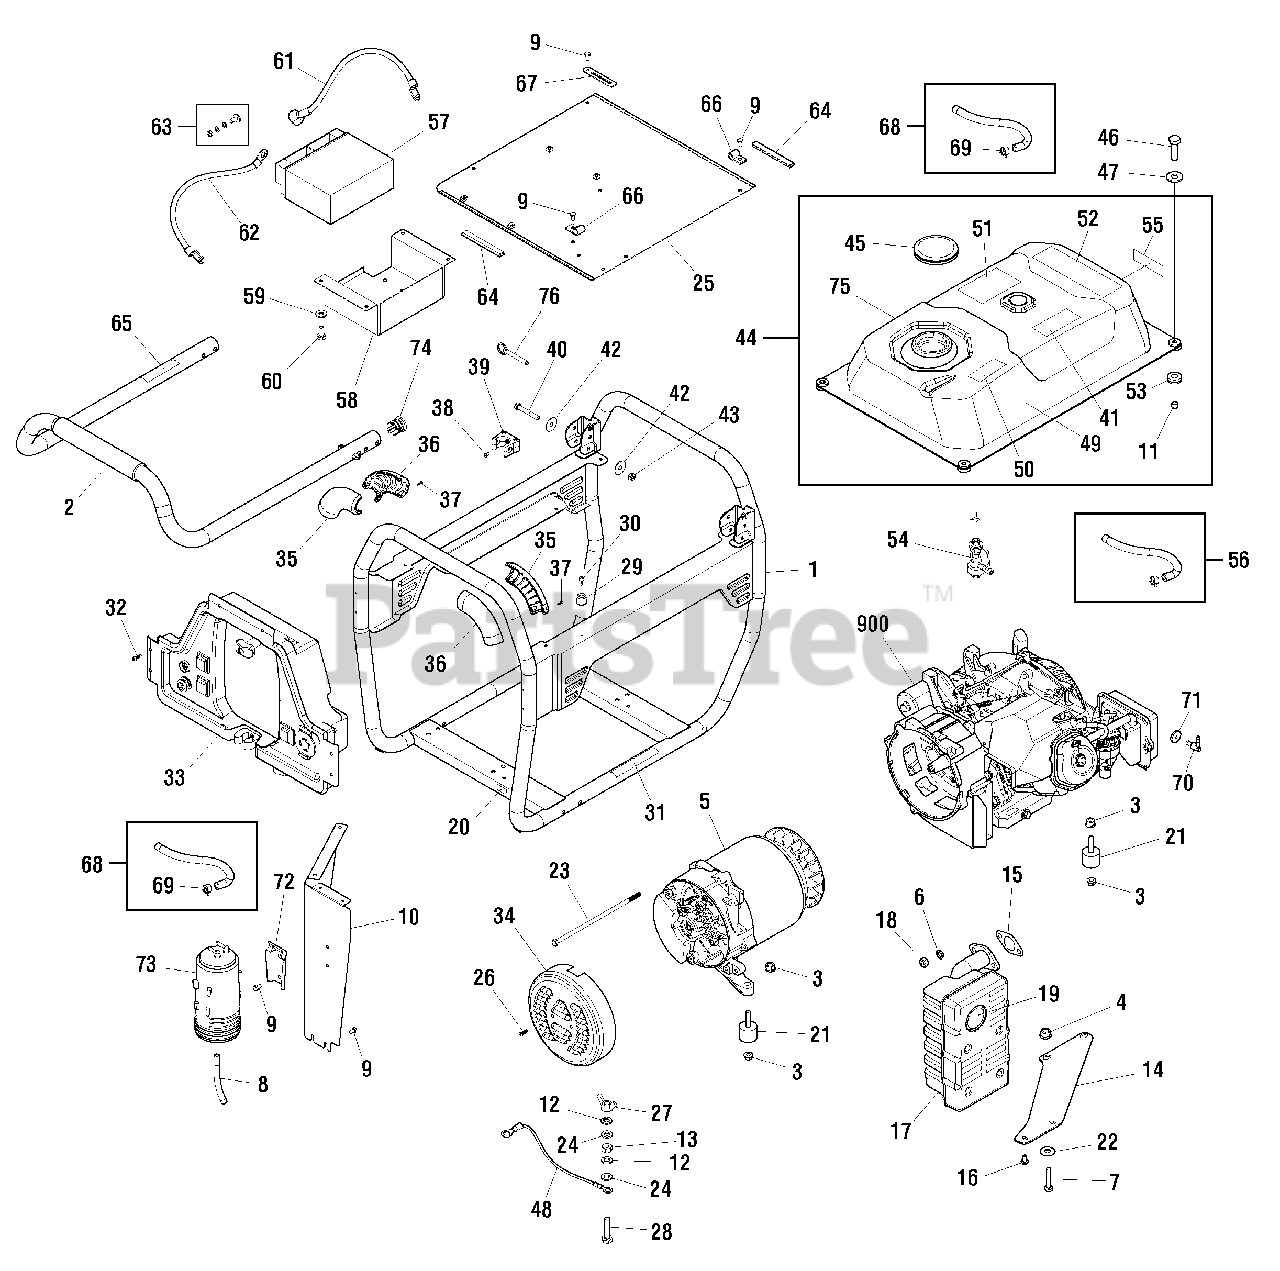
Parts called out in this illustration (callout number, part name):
5	ALTERNATOR
6	* WASHER, Lock, 3/8
7	* CAPSCREW, Hex Head, M10-1.5 x 45
8	HOSE-FUEL
9	* CAPSCREW, Hex Head, M6-1.0 x 10
12	* WASHER, Lock, 1/4
13	* NUT, M6-1.0
15	GASKET-EXHAUST
16	* CAPSCREW, Hex Head, M6-1.0 x 12
18	* NUT, M8 - 1.25
21	MOUNT-VIBRATION
22	WASHER
24	* WASHER, M6
28	* CAPSCREW, Hex Head, M6-1.0 x 25
33	PANEL-CONTROL
34	COVER-REAR BEARING
47	* WASHER, Flat, 1/4
56	KIT-FUEL HOSE (Cut to fit)
63	KIT-BATTERY HARDWARE
68	HOSE-VAPOR (Cut to fit)
900	** ENGINE
